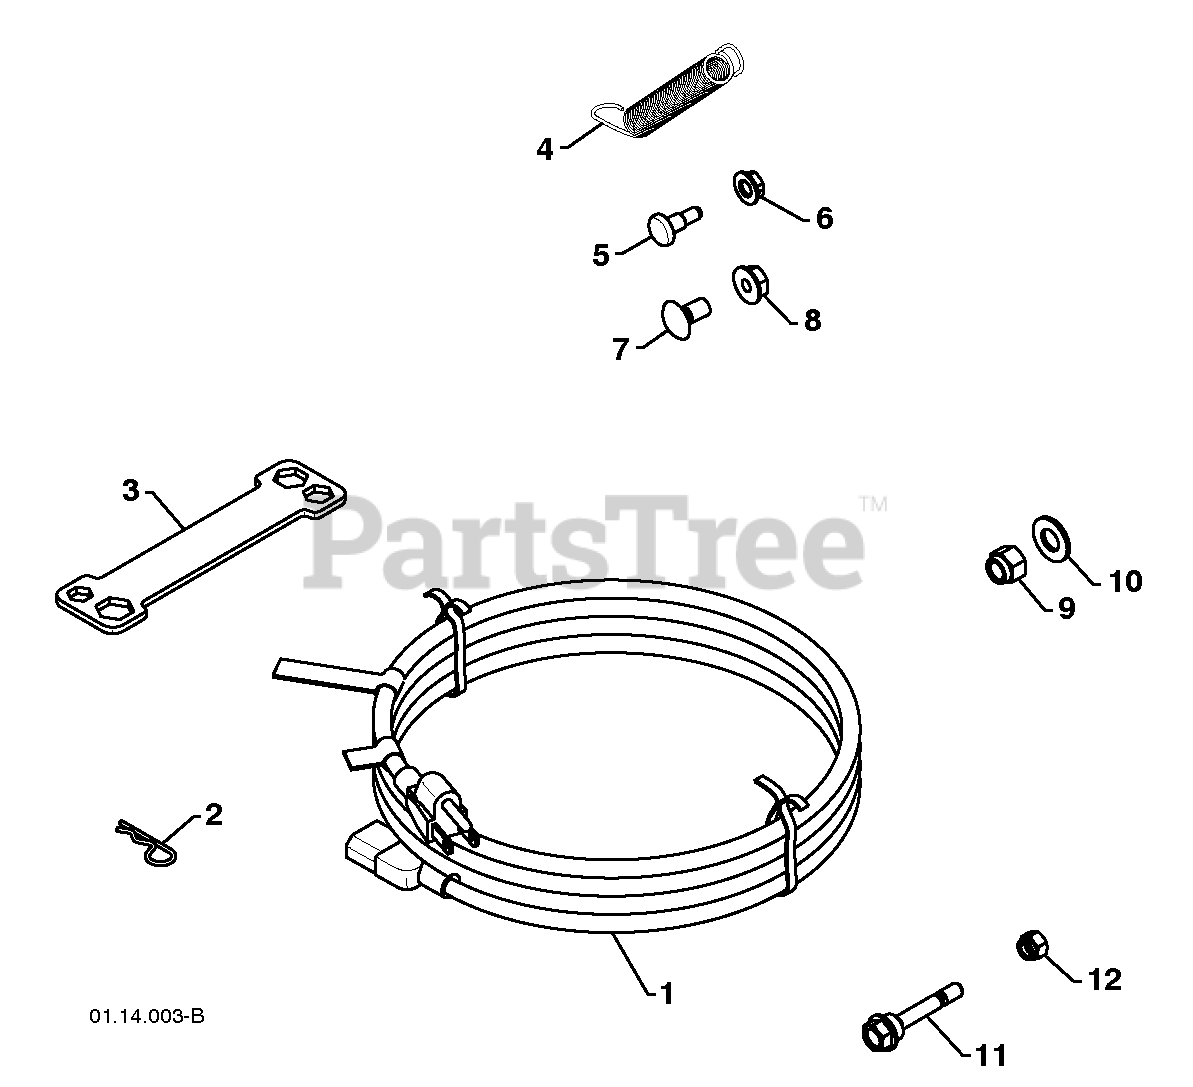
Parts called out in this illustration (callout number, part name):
1	POWER CORD
2	RETAINER PIN
3	WRENCH
4	REMOTE SPRING
5	SHOULDER BOLT 1/4-20
6	LOCKNUT 1/4-20
7	CARRIAGE BOLT 5/16-18 X 5/8
8	LOCKNUT 5/16-18
9	LOCKNUT 3/8-16
10	WASHER 3/8
11	SHEAR BOLT 1/4-20 X 1-13/16
12	LOCKNUT 1/4-20
